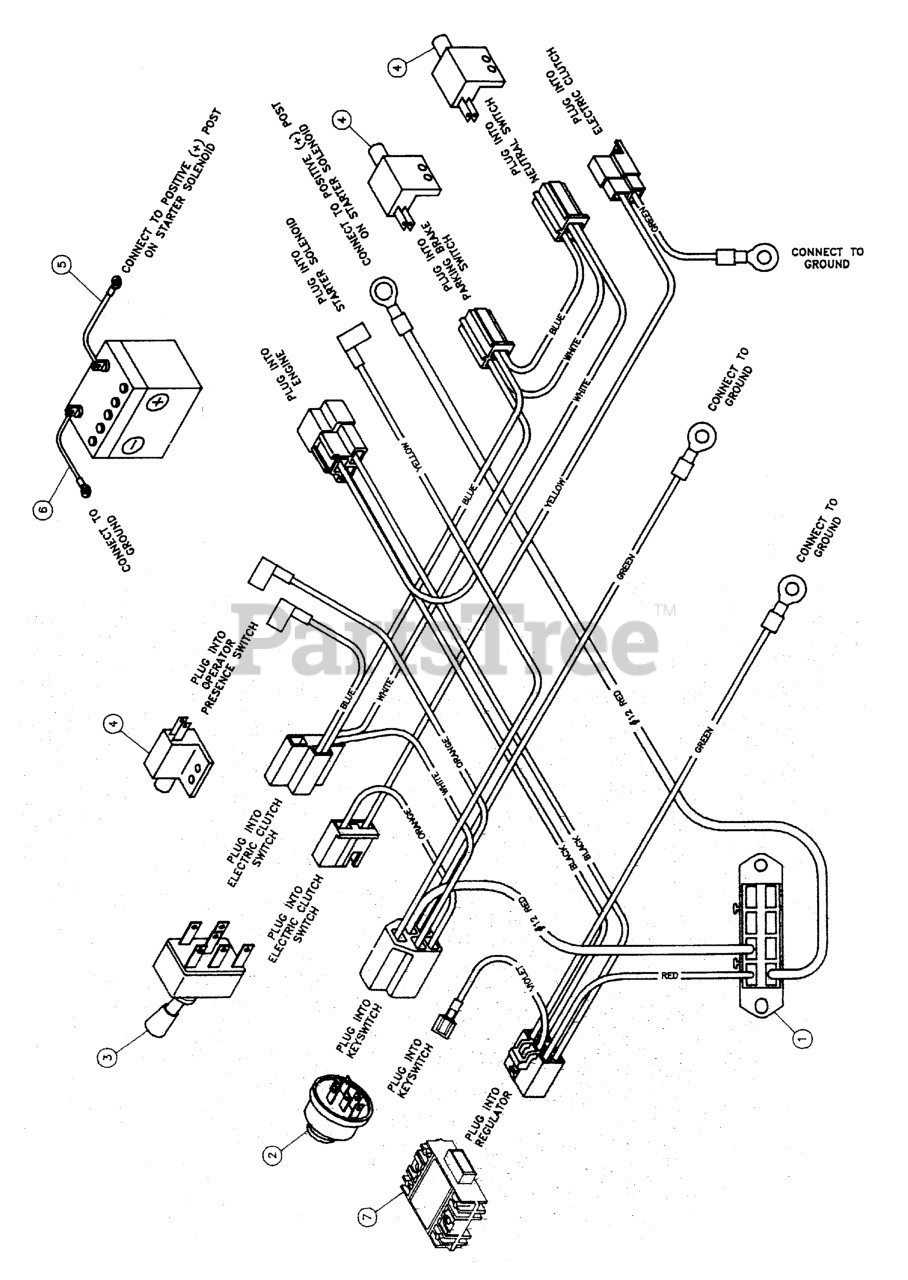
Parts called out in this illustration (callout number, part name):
2	SWITCH, IGNITION, 6 POST
3	SWITCH, Electric Clutch
4	SWITCH, PLUNGER, N.C.
5	POSITIVE (+) BATTERY CABLE, 30"
6	BATTERY CABLE, NEG, 22, 1/4-5/16
